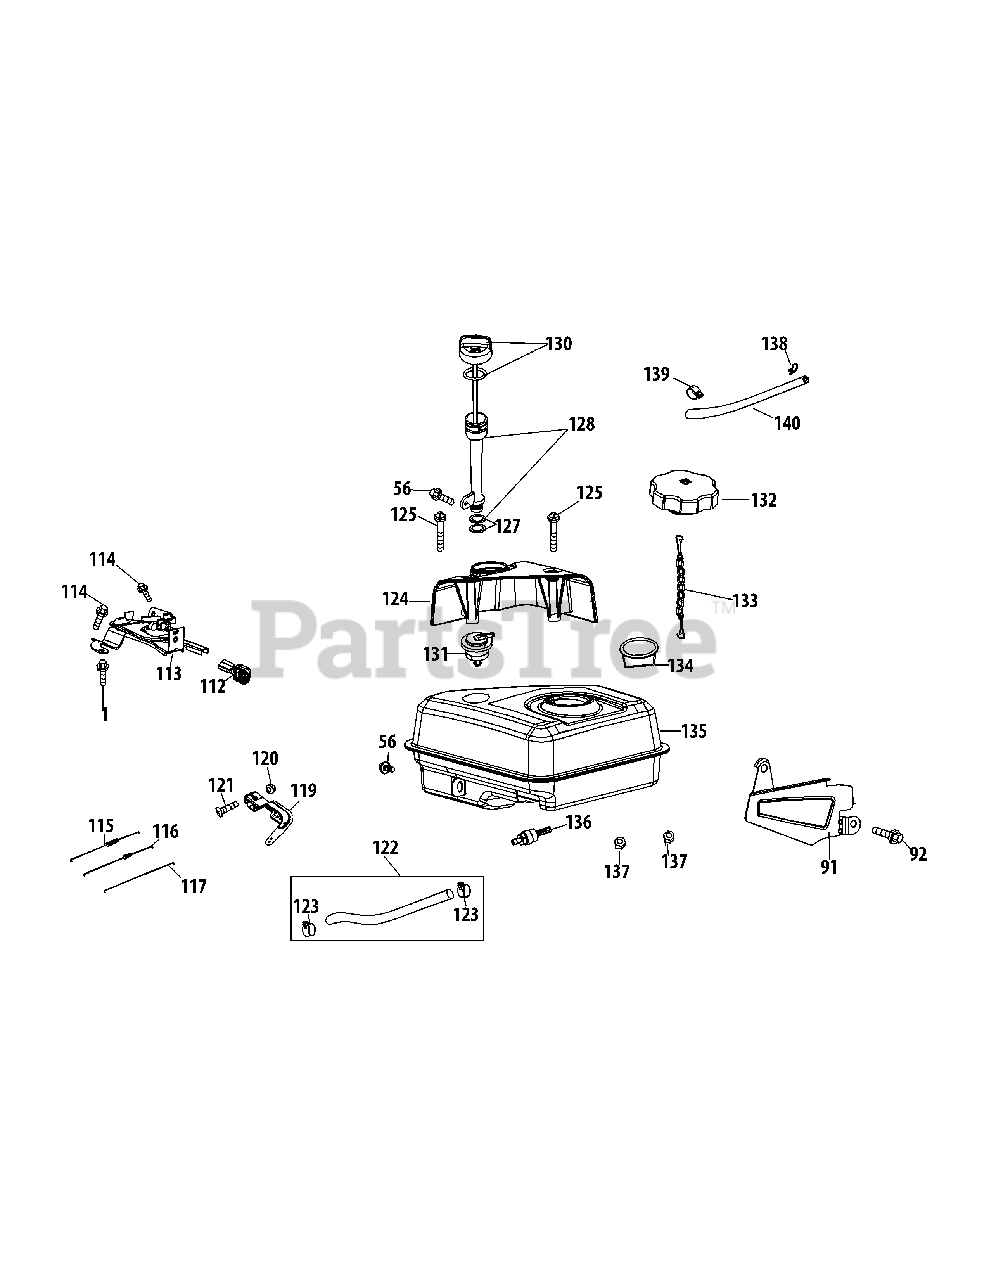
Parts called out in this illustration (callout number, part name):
1	Bolt M6×16
56	Bolt M6×12
91	Air Flow Shield
92	Bolt M6×10
112	Throttle Control Knob
113	Primer Bracket
114	Bolt M6×12
115	Governor Spring
116	Throttle Linkage Spring
117	Throttle Linkage
119	Governor Arm
120	Nut M6
121	Governor Arm Bolt
122	Kit-Fuel Line
123	Fuel Hose Clamp
124	Dipstick Decoration Cover
127	Oil Fill Tube O-Ring 15×1.5
128	Oil Fill Tube Assy
130	Dipstick Assy
131	Roll Over Valve
132	Cap Comp,Fuel
133	Fuel Cap Chain
134	Fuel Filter
135	Fuel Tank Assembly
136	Fuel Tank Nipple
137	Nut M6
138	Hose Clamp
139	Hose Clamp
140	Primer Hose Assembly
